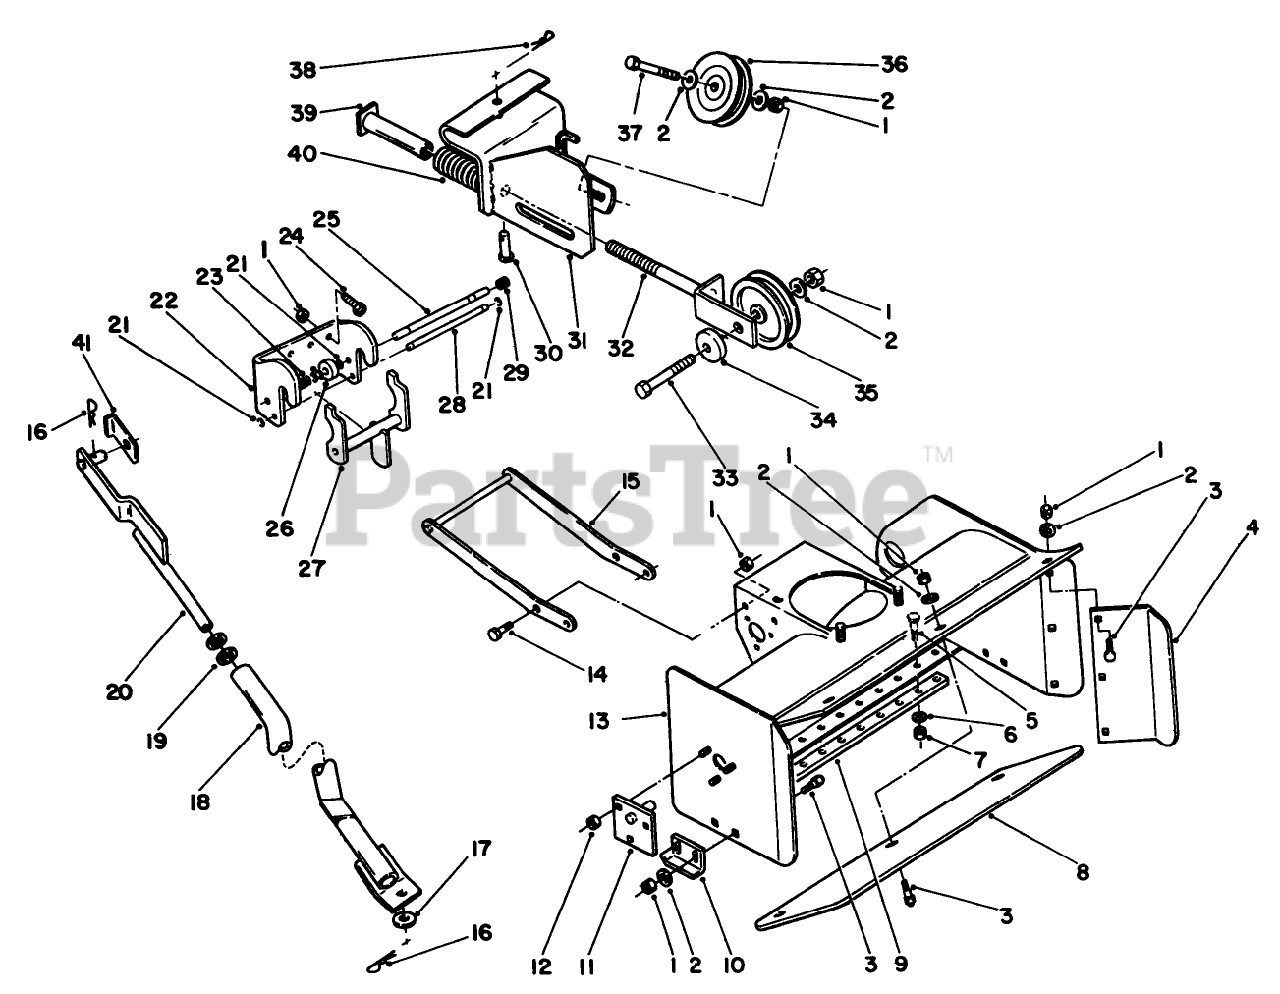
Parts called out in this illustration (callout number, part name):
1	NUT-LOCK, NI
2	WASHER-FLAT
3	BOLT-CARR
6	NUT-LOCK, NI
7	NUT-LOCK, NI
12	NUT-LOCK, NI
14	SCREW-HH
16	PIN-COTTER
17	WASHER-FLAT
19	WASHER
21	RING-RETAINING
23	SPRING
24	SCREW-CARR
25	ROD-LOCK
28	ROD-LATCH PIVOT
29	CAP-ROD, PLUNGER
30	Pin-Clevis
32	IDLER-SLIDE W.A. *B
33	SCREW-HH
34	BUSHING
37	SCREW-HH
38	PIN-HAIR
